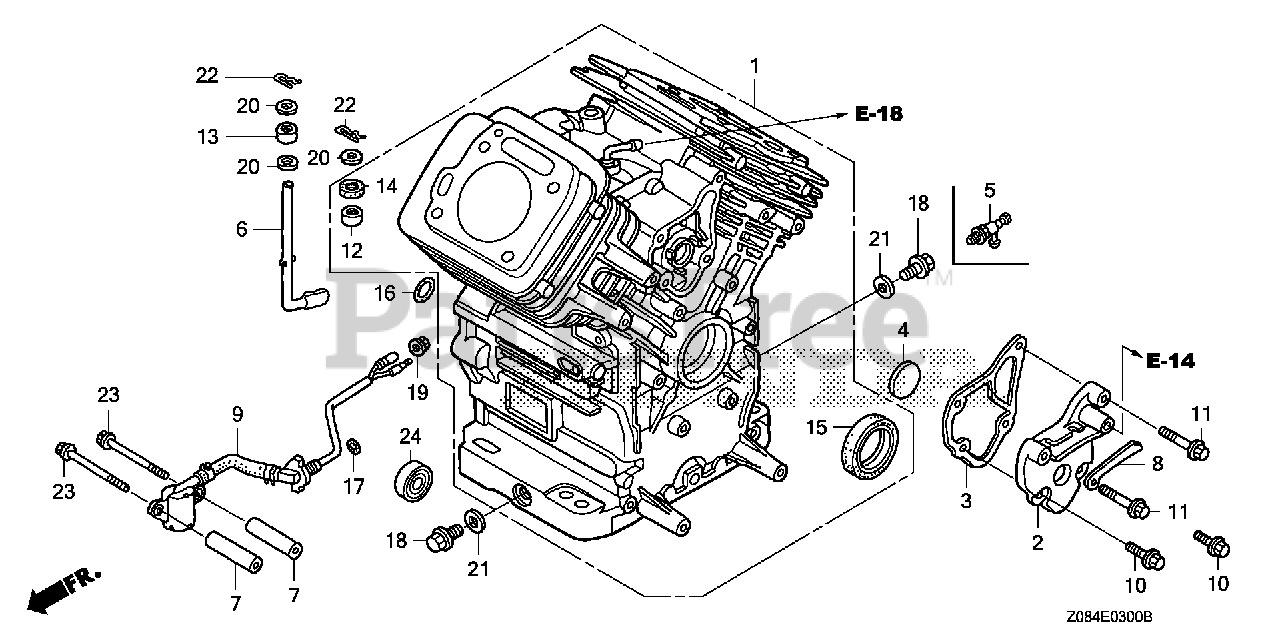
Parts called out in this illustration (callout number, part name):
1	CYLINDER ASSY.
2	COVER, BREATHER
3	GASKET, BREATHER COVER
4	VALVE, BREATHER
5	VALVE, DRAIN (14X1.5)
6	SHAFT, GOVERNOR ARM
7	COLLAR, FILTER SETTING
8	CLAMP, WIRE
9	SWITCH ASSY., OIL LEVEL
10	BOLT, FLANGE (6X16) (CT200)
11	BOLT, FLANGE (6X32) (CT200)
12	BEARING, NEEDLE (8X12.7X11.1)
13	BEARING, NEEDLE (8X12X10)
14	OIL SEAL (8X14X5)
15	OIL SEAL (38X58X9)
16	O-RING (13X3.0)
17	O-RING (14MM) (ARAI)
17	O-RING (14MM) (NOK)
18	BOLT, DRAIN PLUG (14MM)
19	NUT, FLANGE (10MM)
20	WASHER, PLAIN (8MM)
21	WASHER, DRAIN PLUG (14MM)
22	PIN, LOCK (8MM)
23	BOLT, FLANGE (6X75)
24	BEARING, RADIAL BALL (6003)
